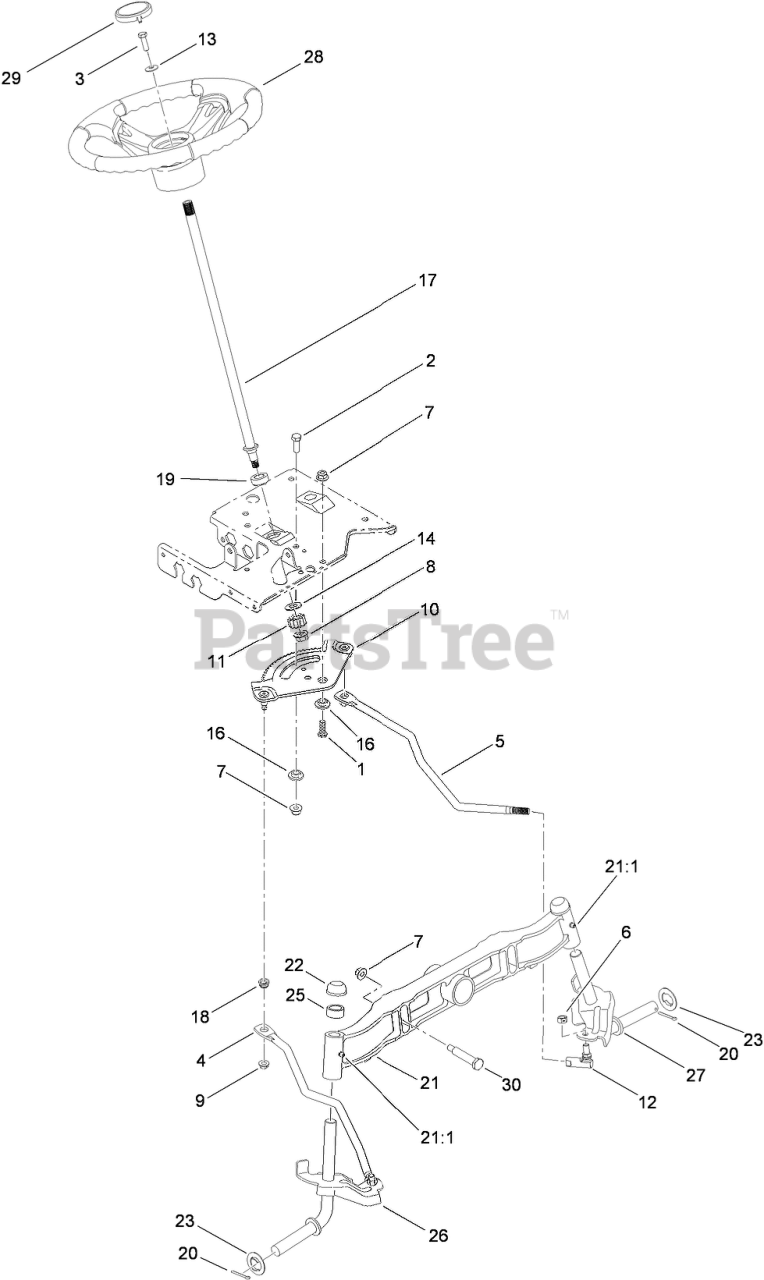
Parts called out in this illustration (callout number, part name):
1	SCREW-HH
2	SCREW-HH
3	SCREW-HH
4	LINK-DRAG, RH
5	LINK-DRAG, LH
6	NUT-HEX, LOCK
7	NUT-LOCK, FLANGE
8	NUT-LOCK, FLANGE
9	NUT-LOCK, FLANGE
10	GEAR-STEERING
11	GEAR-PINION, STEERING
12	BALL JOINT ASM
13	WASHER-FLAT
14	WASHER-FLAT
16	SPACER-SHOULDER
17	SHAFT-STEERING
18	BUSHING
19	BEARING-FLANGE, HEX
20	PIN-COTTER
21	PIVOT-AXLE, CAST IRON
21:1	FITTING-GREASE
23	WASHER-FLAT
25	SPACER
26	RH AXLE ASM
27	LH AXLE ASM
28	3 SPOKE WHEEL STEERING ASM
29	CAP-WHEEL, STEERING
30	BOLT-SHOULDER
